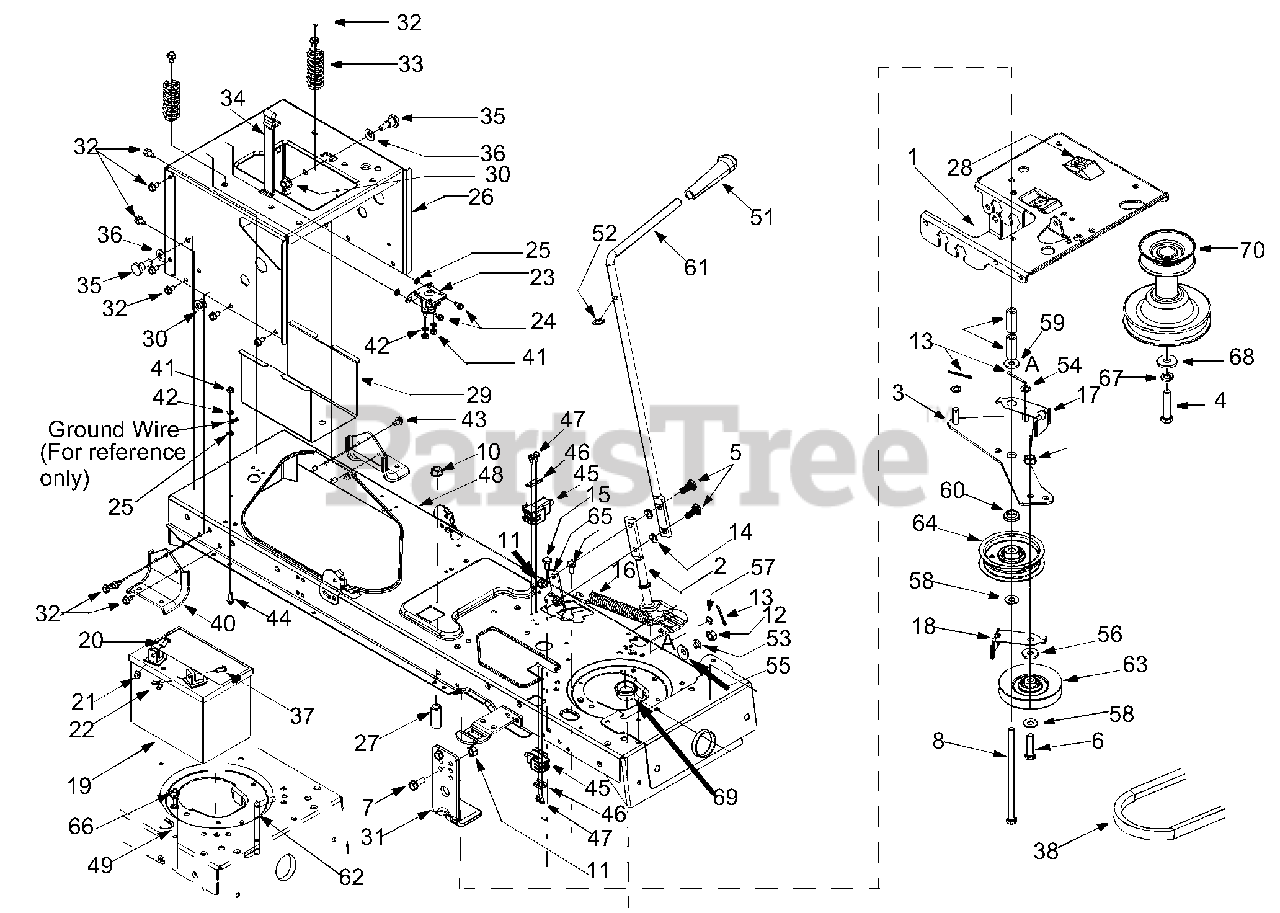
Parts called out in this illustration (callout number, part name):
2	PTO Lever Engagement Assembly
3	Engagement Plate Assembly
4	Hex Bolt 7/16-20 x 2.0
5	Carriage Screw 5/16-18 x 1.0
6	Hex Screw 3/8-16 x 1.5
7	AB Screw, 5/16-12 x .75
8	Hex Screw 3/8-16 x 7.0
10	Flange Lock Nut
11	Flange Lock Nut
13	Cotter Pin
14	Speed Nut
15	Hex Cap Screw 5/16-18 x .625
16	Extension Spring
17	Belt Guard
18	Belt Guard
19	12 V Battery
20	Hex Cap Screw, 1/4-20 x .62
21	Hex Sems Nut, 1/4-20
22	Wing Nut, 1/4-20
23	Solenoid, 12-Volt, 100 Amp
24	Self Tapping Screw, 1/4-20 x .5
25	Lock Washer, 1/4
28	Hex Split Flange Bearing
32	Self Tapping Screw, 5/16-18 x .625
33	Compression Spring, 1.28 x 3.5
34	Battery Strap
35	Shoulder Screw, .625 x .5, 7/16-20
36	Bell Washer, .45 x 1.0 x .062
37	Shoulder Screw
38	PTO Belt
41	Hex Nut 1/4-20
42	Lock Washer
43	TT Screw 5/16-18 x 0.5
44	TT Screw 1/4-20 x 0.75
45	Switch
46	Switch Plate
47	AB Screw #10-16 x 0.5
50	Push Nut Retainer
51	PTO Knob
52	Flat Washer
53	Lock Washer
54	Flat Washer
55	Bell Washer
56	Flat Washer
57	Flat Washer
58	Flat Washer
59	Flat Washer
60	Shoulder Spacer
62	Belt Keeper Rod
63	Idler Pulley
64	Idler Pulley
66	Lock Washer
67	Lock Washer
68	Flat Washer
70	Engine Pulley
